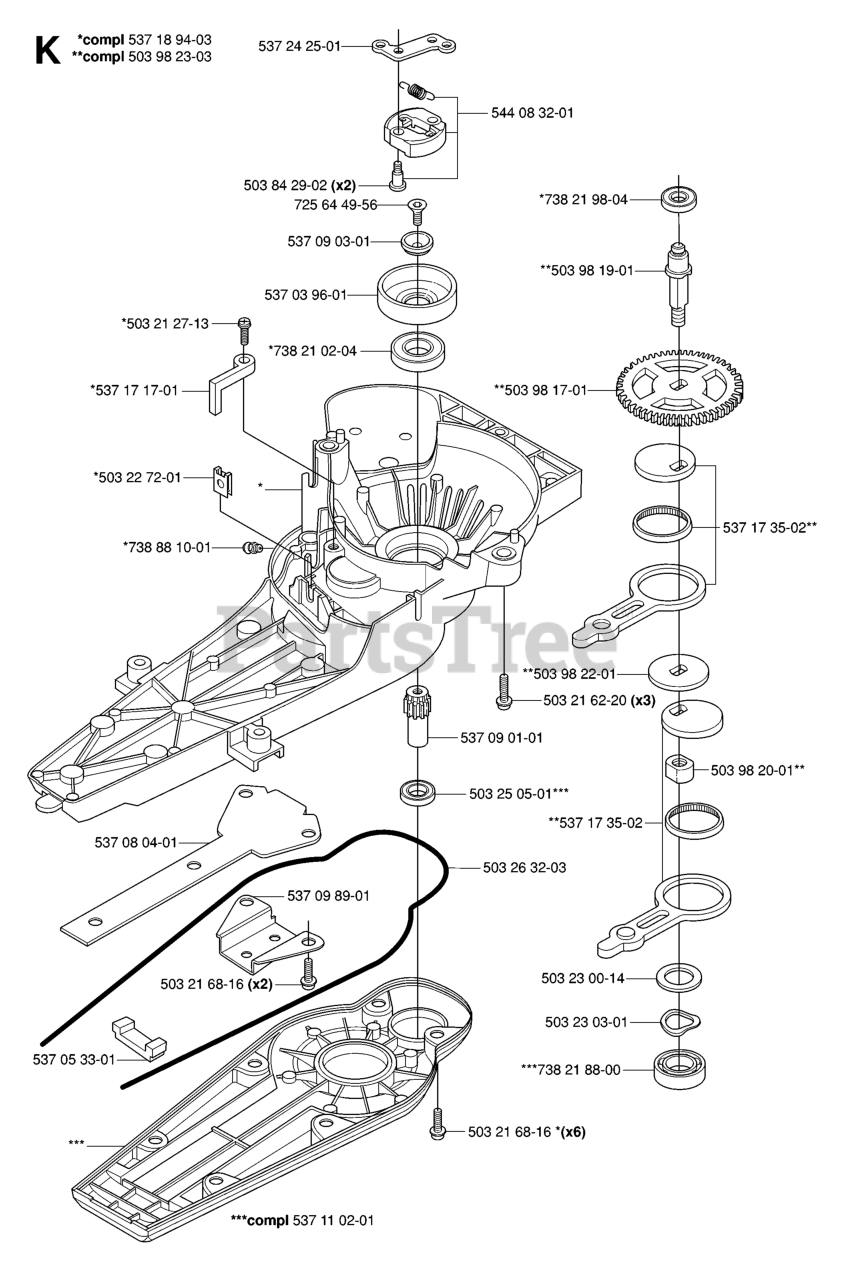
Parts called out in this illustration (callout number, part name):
1	IMPELLER ASSY
2	GEARBOX.ASM.AUGER.D-SHAFT
3	BEARING FLANGE
4	PULLEY.FLANGE.IMPELLER
5	BASE.DISCHARGE.CHUTE
6	BRACKET, CORNER DISCHARGE
7	CLEAN OUT TOOL
8	CLIP.CLEANOUT.TOOL
9	LOCKNUT.NYLOC.1/4-20
10	SCREW.HEX.HD1/4-20X
11	NUTNYLOK.FLRANGE.5/16-18
12	BOLT, HEX HEAD 5/16-18
13	HUB.IMP.PULLEY.D-SHAFT
14	SLEEVE.IMP.PULLEY.D-SHAFT
15	NUT
16	BOLT.CARRIAGE.5/16-18X
17	SCREW.HWH.13-16-5.8.BZP
18	CASE PLUG
19	GEAR.BOX.COVER.RIGHT.SIDE
20	GASKET.GEAR.BOX
21	OIL SEAL
22	FLANGE BUSHING-1"
23	WASHER TRUST 1"
24	WORM GEAR
25	AUGER SHAFT
26	KEY, SQUARE 1/4 X .875
27	FLANGE BUSHING-5/8
28	WASHER, THRUST 5/8
29	SHAFT.IMPELLER.D-SHAFT
30	PIN, ROLL 3/16 X 1-1/8
31	WASHER, THRUST 3/4
32	BEARING TRUST 3/4 NTA-1220
33	BUSHING, FLANGE 3/4
35	HEX SCREW-5/16 X 3/4
36	GEAR.BOX.COVER.LEFT.SIDE
37	BOLT.SHOULDER.SHEAR.1/4-20.
